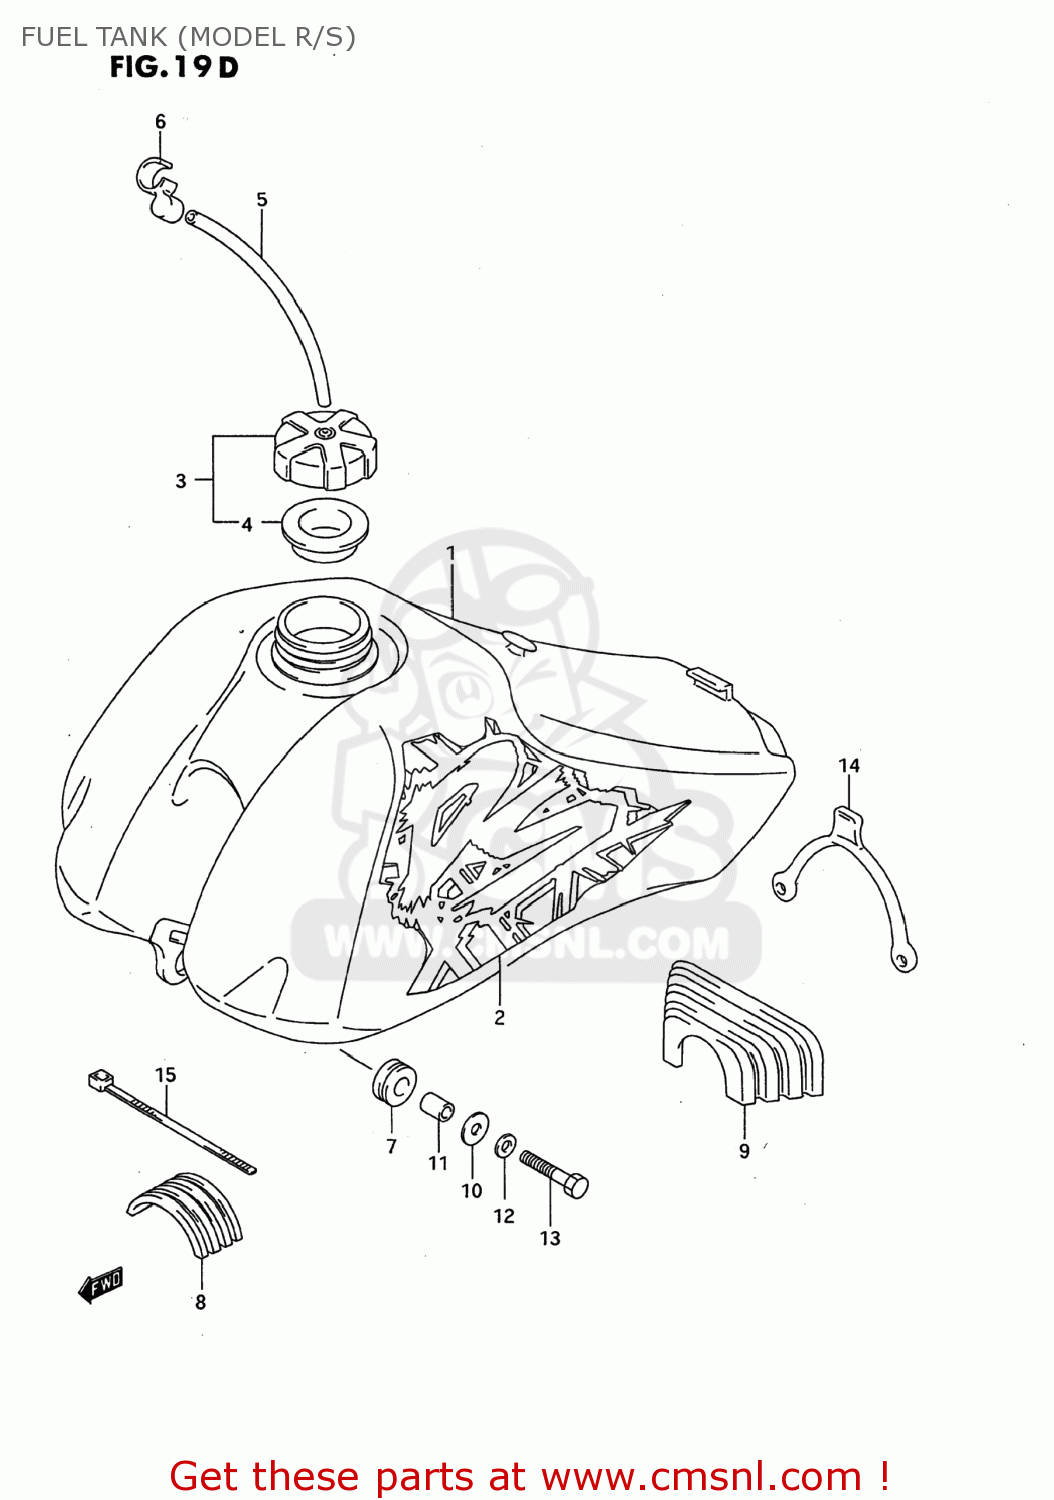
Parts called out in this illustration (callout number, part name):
1	TANK ASSY,FUEL(YELLOW)
2	EMBLEM SET,FUEL TANK
3	CAP SET,FUEL TANK
4	GASKET (NAS)
5	HOSE(5X8.2X600)
6	CLAMP
7	CUSHION
8	CUSHION,FUEL TANK UPR FR
9	CUSHION,FUEL TANK UPR RR
10	WASHER (6.5X24X1.6)
11	SPACER (6.5X10.5X13.5)
12	WASHER,LOCK
13	BOLT
14	BAND,FUEL TANK RR
15	CLAMP
